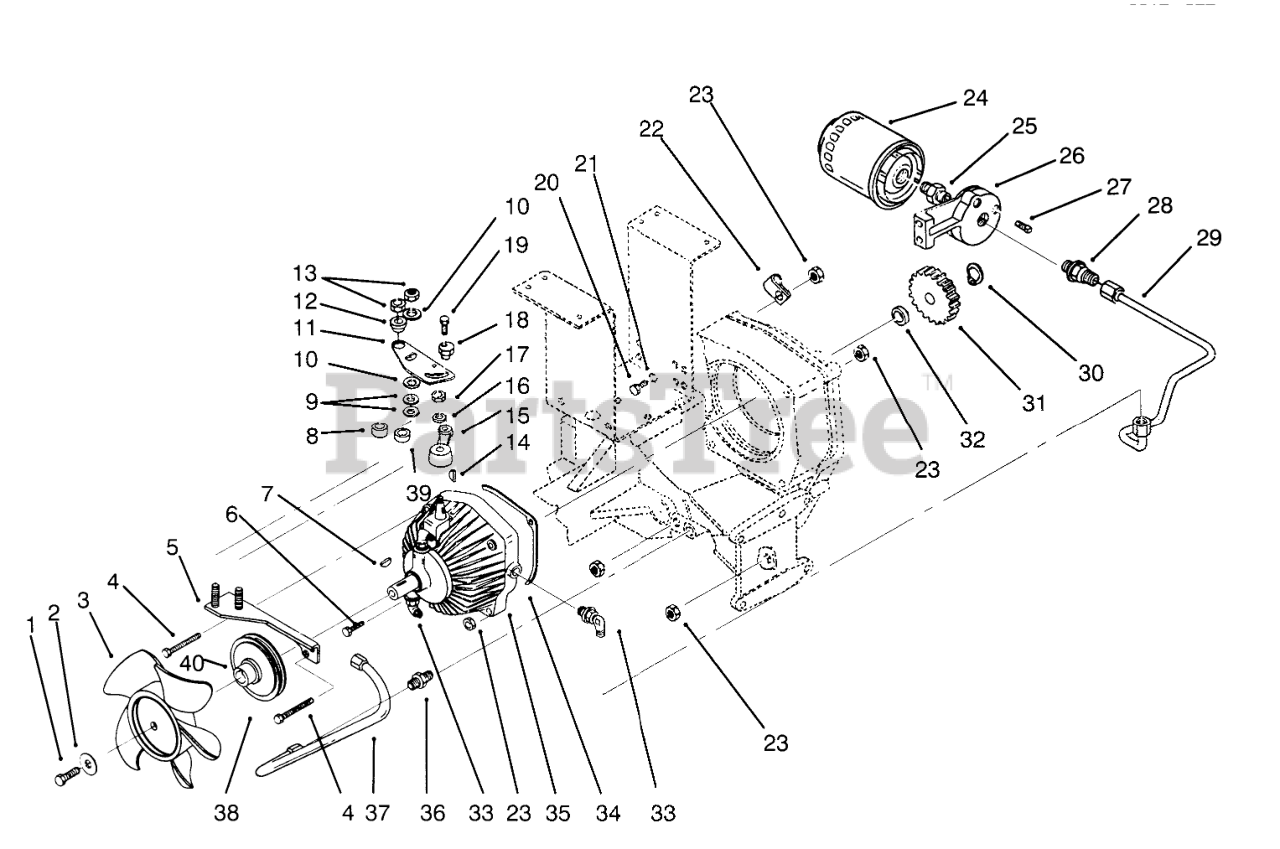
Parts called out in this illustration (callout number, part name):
1	SCREW-HEX HD CAP
2	WASHER
3	NYLON FAN-L-CW
4	SCREW-HH
5	ASSY-PLATE B
7	KEY-WOODRUFF
8	SPACER-PIVOT
9	WASHER-SPRING DISC
10	FRICTION WASHER
11	CAM-SPEED CONTROL (NS)
12	CAM-SPACER
14	KEY-WOODRUFF
15	ARM-SPEED CONTROLB
16	WASHER-FLAT
17	NUT-LOCK, NI
19	Screw-HH
20	SCREW-HH
21	WASHER-LOCK
22	CLIP
23	NUT-LOCK, NI
24	OIL FILTER ASM
25	FITTING
26	BASE-FILTER
28	Fitting-Hyd., Straight (Incl. "O"Ring)
29	ASS'Y-TUBE FILTER
30	RING-SNAP, EXTERNAL
31	GEAR 20 TEETH DRIVE
32	SPACER GEAR
33	ELBOW
34	GASKET
35	Pump & Motor
36	FITTING-TUBE
37	ASSY-TUBE SUCTION
38	PULLEY
39	SPACER-FRICTION
